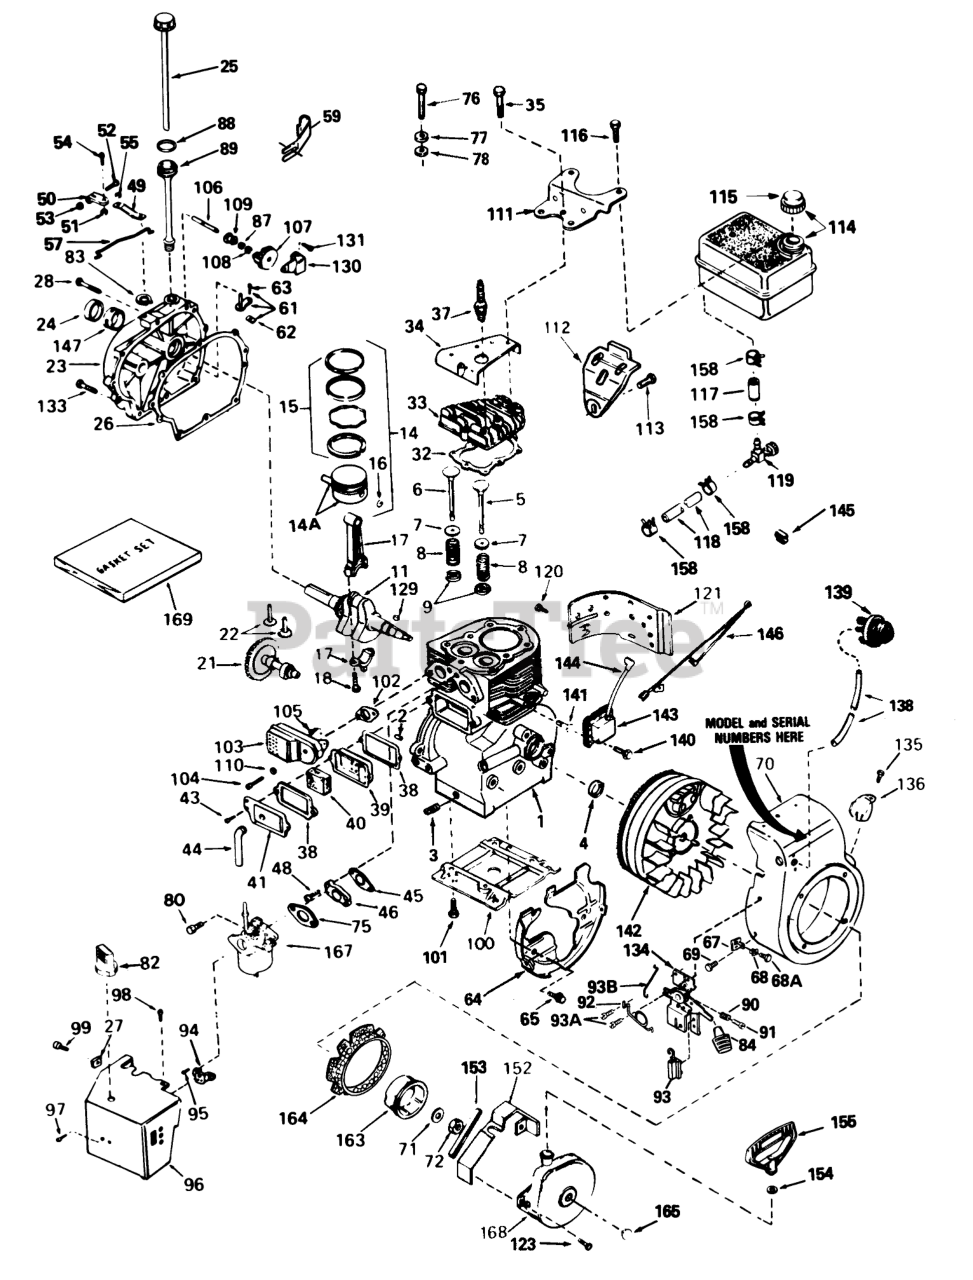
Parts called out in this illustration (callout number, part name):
1	Clyinder (Incl.Ref. #2-4)
2	Pin-Dowel
3	Plug-Drain, Oil (SQH 1/4-18)
4	Oil Seal
5	Valve-Intake (Std.)(Incl. Ref. #9)
6	Valve-Exhaust (Std.)(Incl. Ref. #9)
7	Cap-Spring, Valve
8	Spring-Valve
9	Keeper-Spring, Valve
11	Crankshaft
14	Piston Pin & Ring Assy. (Std.)(Incl. Ref. #14A-16)
14A	Piston & Pin Assy. (Std.)(Incl. Ref. #16)
15	Ring Set (Std.)
16	Ring-Retaining, Piston Pin
17	Connecting Rod Assy. (Incl. Ref. #18)
18	Bolt-Connecting Rod
21	55012A GIL SNWTHWR
22	Lifter-Valve
23	Cylinder Cover Assy. (Incl. Ref. #24, 106 & 147)
24	Oil Seal
25	Dipstick
26	Gasket-Cover, Cylinder
27	Nut-U Type
28	Screw (1/4-20 x 1-1/4)
32	Gasket-Head, Cylinder
33	Head-Cylinder (Incl. 3 Ref. #35)
34	Cover-Head, Cylinder
35	Screw (5/16-18 X 2-1/2)
37	Spark Plug-Resistor (R J19 L M)
38	Gasket-Breather
39	Body-Breather
40	Element-Breather
41	Cover-Valve
44	Tube-Breather
45	Gasket-Intake
46	Flange-Carburetor (Incl. Ref. #80)
49	Lever-Governor
50	Clamp-Lever, Governor
51	Nut-Lock
53	Nut-Lock
54	Screw
55	Washer-Lock
57	Governor Link
59	Clip-Tube, Fill
61	Governor Rod Assy. (Incl. Ref. #62-63)
62	Yoke-Governor
63	Screw (6-40x5/16)
64	Baffle-Blower Housing
65	Screw (1/4-20x19/32)
67	Bracket
68	Grommet
68A	Screw (8-32 x 3/8)
70	Blower Housing Assy. (Incl. Ref #135-136)
71	Washer-Belleville
72	Flywheel Nut
75	Gasket-Carburetor
76	Screw (5/16-18 X 2-1/2)
77	Washer-Belleville
78	Washer-Flat
80	Screw-Hex Hd.
82	Knob-Choke
83	Ring-Retaining
84	Knob-Control
87	Washer-Flat
89	Tube-Fill, Oil
90	Spring-Compression
91	Screw
92	Spring-Throttle
93	Terminal
93A	Screw (10-32 x 1/2)
93B	Link-Throttle
94	Bracket-Choke
95	Screw (10-32 x 1/2)
96	Carburetor Cover
97	Screw (8-32 X 5/16)
98	Screw (10-32x1/2)
99	Screw (8-32 x 3/8)
100	Base Engine
102	Gasket Exhaust
103	Muffler
104	Screw (5/16-18 X 2)
106	Shaft-Governor
107	Governor Gear Assembly (Incl. Ref. #87)
108	Ring-Retaining
109	Spool-Governor
111	Bracket-Fuel Tank
112	Bracket-Fuel Tank
113	Screw (1/4-20x19/32)
114	Tank-Fuel (Incl. Ref. #115)
115	Cap, Fuel
116	Screw (1/4-15x7/8)
117	Line-Fuel
118	Line-Fuel (8.62)
119	Valve-Shut Off
121	Extension-Blower Hsng.
129	Key-Flywheel
130	Bracket, Governor
131	Screw (10-24x1/2)
134	Remote Speed Control Assy. (Incl. Ref. #90-93)
135	Screw (8-32 x 3/8)
138	Line-Primer
139	Primer-Asm
140	Screw
141	Stud
142	Flywheel
143	Solid State
144	Cover-Spark Plug
145	Clip-Wire
146	Ground Wire
147	Bushing-Crankshaft
152	Guard-Starter
153	Seal, Snowguard
155	Handle-Starter, Mitten Grip
158	Clamp-Line, Fuel
163	Cup-Starter
164	Screen-Starter
165	Plug-Starter
167	Carburetor Assembly (Incl. Ref. #75)
168	Starter-Rewind
169	Gasket Set
